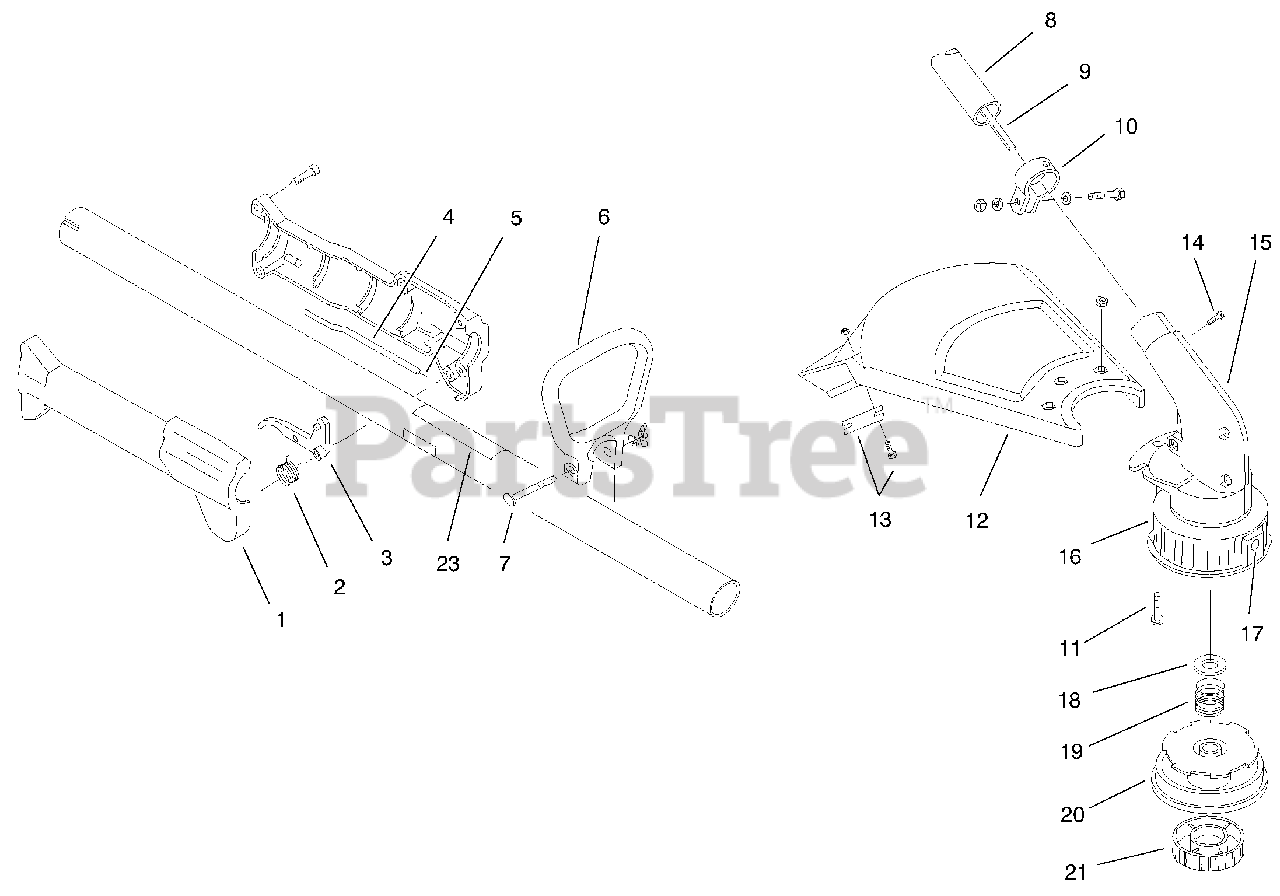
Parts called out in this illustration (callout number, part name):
1	Throttle Housing & Trigger Asm.
2	Throttle Trigger Spring
3	Throttle Trigger
4	Throttle Cable Housing Asm.
5	Throttle Cable
6	D-Handle
7	D-Handle Hardware Asm.
8	Drive Shaft Housing Asm.
9	Flexible Drive Shaft
10	Lower Clamp Asm.
11	Guard Mounting Screw Asm.
12	Guard and Blade Asm.
13	Blade Asm.
14	Anti-Rotation Screw
15	Gearbox Asm.
16	Outer Spool and Eyelet Asm
18	Retainer
20	Inner Reel
21	Bump Head Knob Asm.
23	Decal-Safety Symbols
